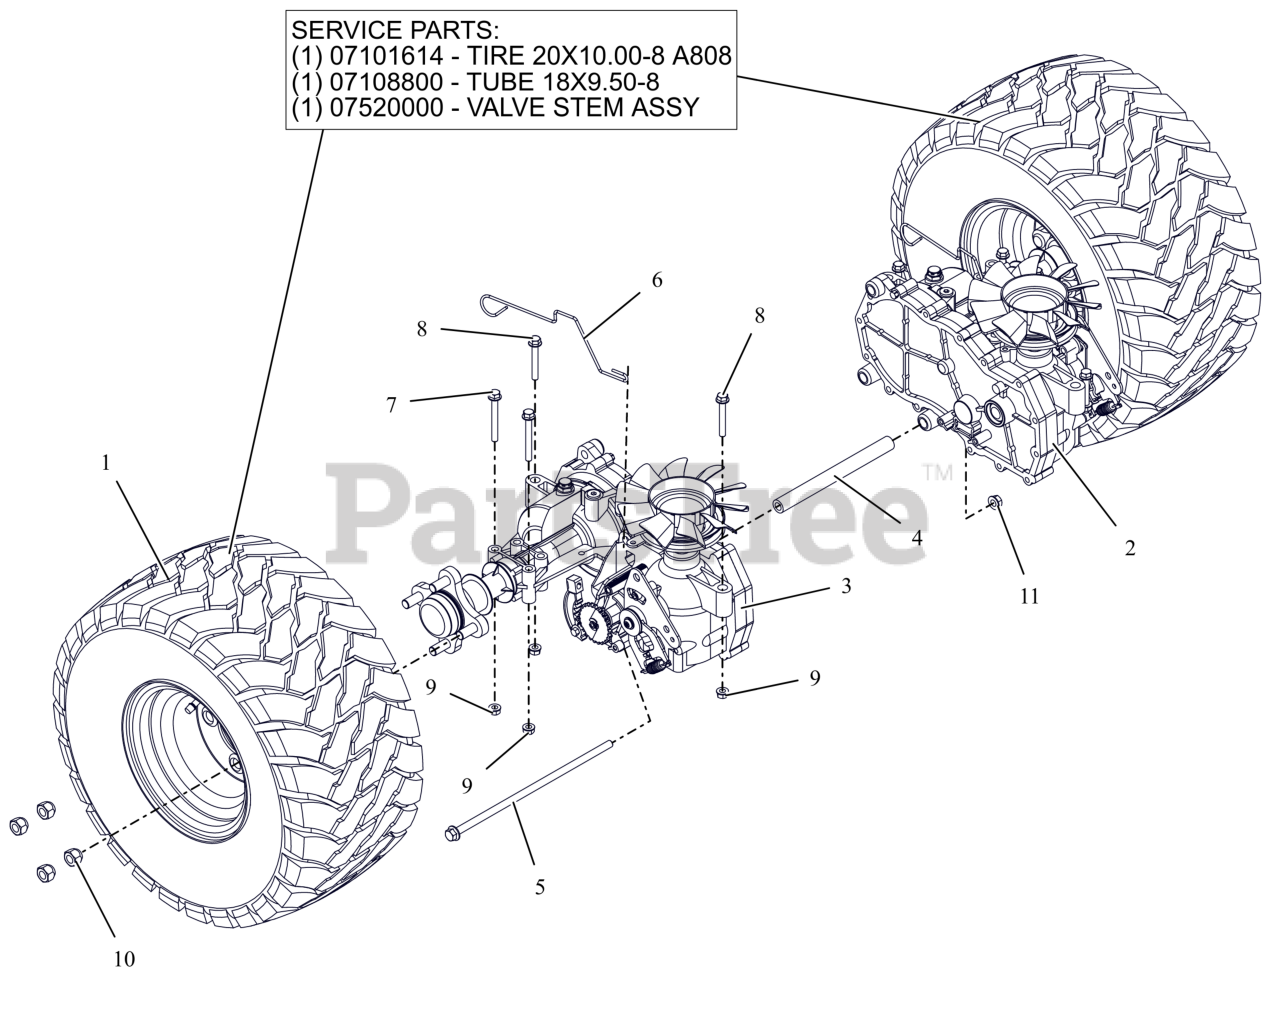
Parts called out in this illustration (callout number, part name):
1	ASM-WHL/TIRE 20X10.00-10 K505
1	TIRE 20X10.00-8 A808 TREAD
1	VALVE STEM ASS'Y
1	TIRE TUBE 18/6.50/8.50/9.50-8, 20/8.00/10.00-8 4 PLY TR13 STRAIGHT VALVE
2	TRANSAXLE- EZT - LH
3	TRANSAXLE- EZT-RH
4	TUBE, TRANSAXLE BRACE 8.18LG
5	BLT,HEX-FLG .38-16X11.5 G5 ZCC
6	WIRE- DUMP VALVE LEVER
7	BLT,HEX-FLG .31-18X2.75 G5 ZCC
8	BLT,HEX-FLG .31-18X2.25 G5 ZCC
9	NUT,LK-CTR-FLG .31-18 GF ZCC
10	NUT, WHEEL .50-20 ZCC
11	NUT-LK-CTR-FLG .375-16 GF ZCC
